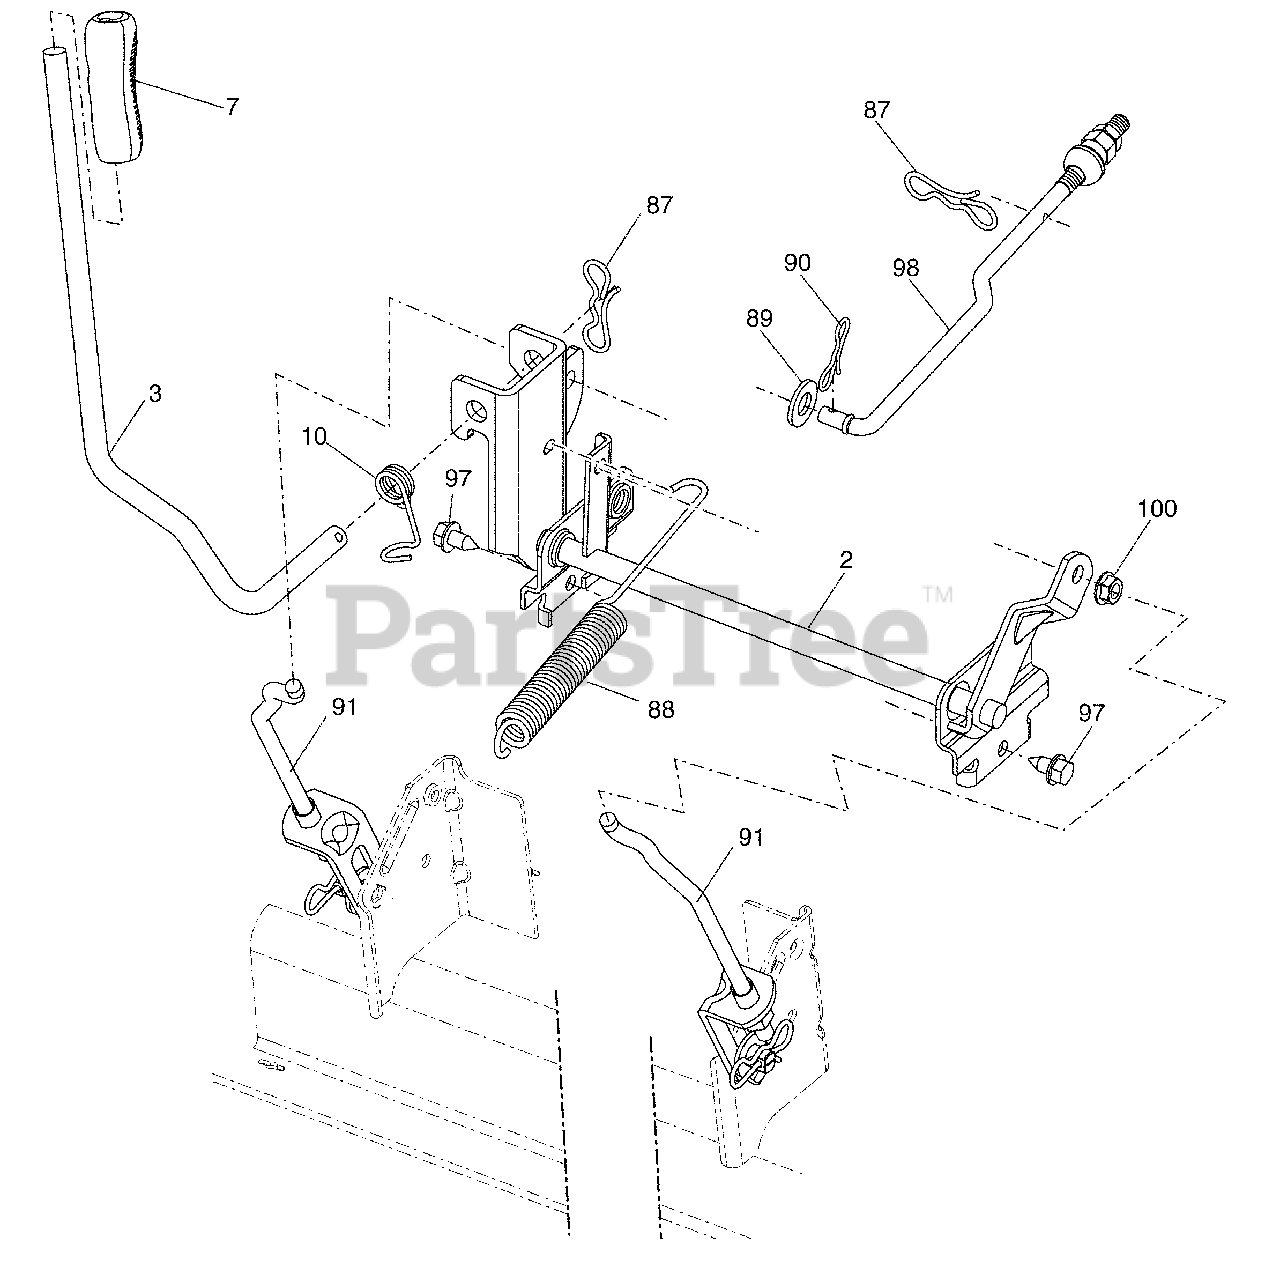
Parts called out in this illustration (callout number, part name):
2	Shaft Asm., Lift
3	Lever Asm., Lift Rh
7	Grip, Lever
10	Spring Torsion
87	Pin Cotter 7/16 Bow Tie Lock
88	Spring Lift Assist
89	Washer Clear Zinc
90	Pin Cotter 5/16 Bow Tie Lock
91	Link Lift Susp Mower Rear
97	Screw 3/8-16 x .75 Smgml Tap/R.Z
98	Link Lift Susp. Front Mower
100	Nut Center Lock 3/8-16 UNC
